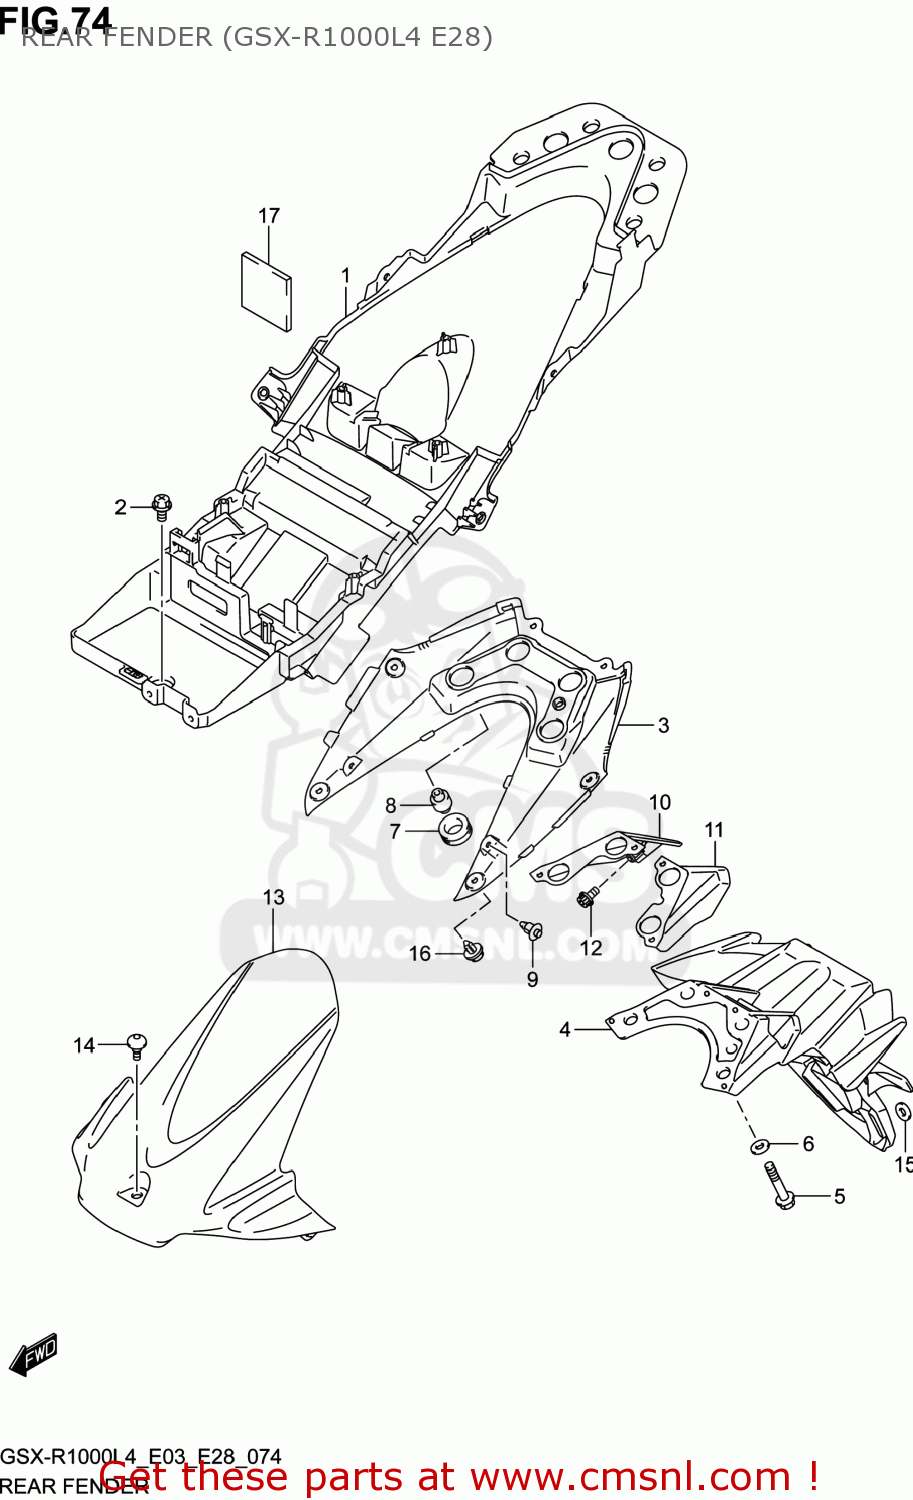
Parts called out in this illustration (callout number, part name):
1	FENDER,RR FR
2	BOLT(6X12)
3	COVER,RR FENDER FR
4	FENDER,RR RR
5	BOLT(6X30)
6	WASHER(6.5X18X1)
7	CUSHION
8	SPACER,RR FENDER RR
9	CLIP(BLACK)
10	COVER,RR FENDER RR,R
11	COVER,RR FENDER RR,L
12	BOLT
13	FENDER,RR LWR
14	SCREW(6X16)
15	WASHER
16	CLIP
17	PROTECTOR(50X50X5)
